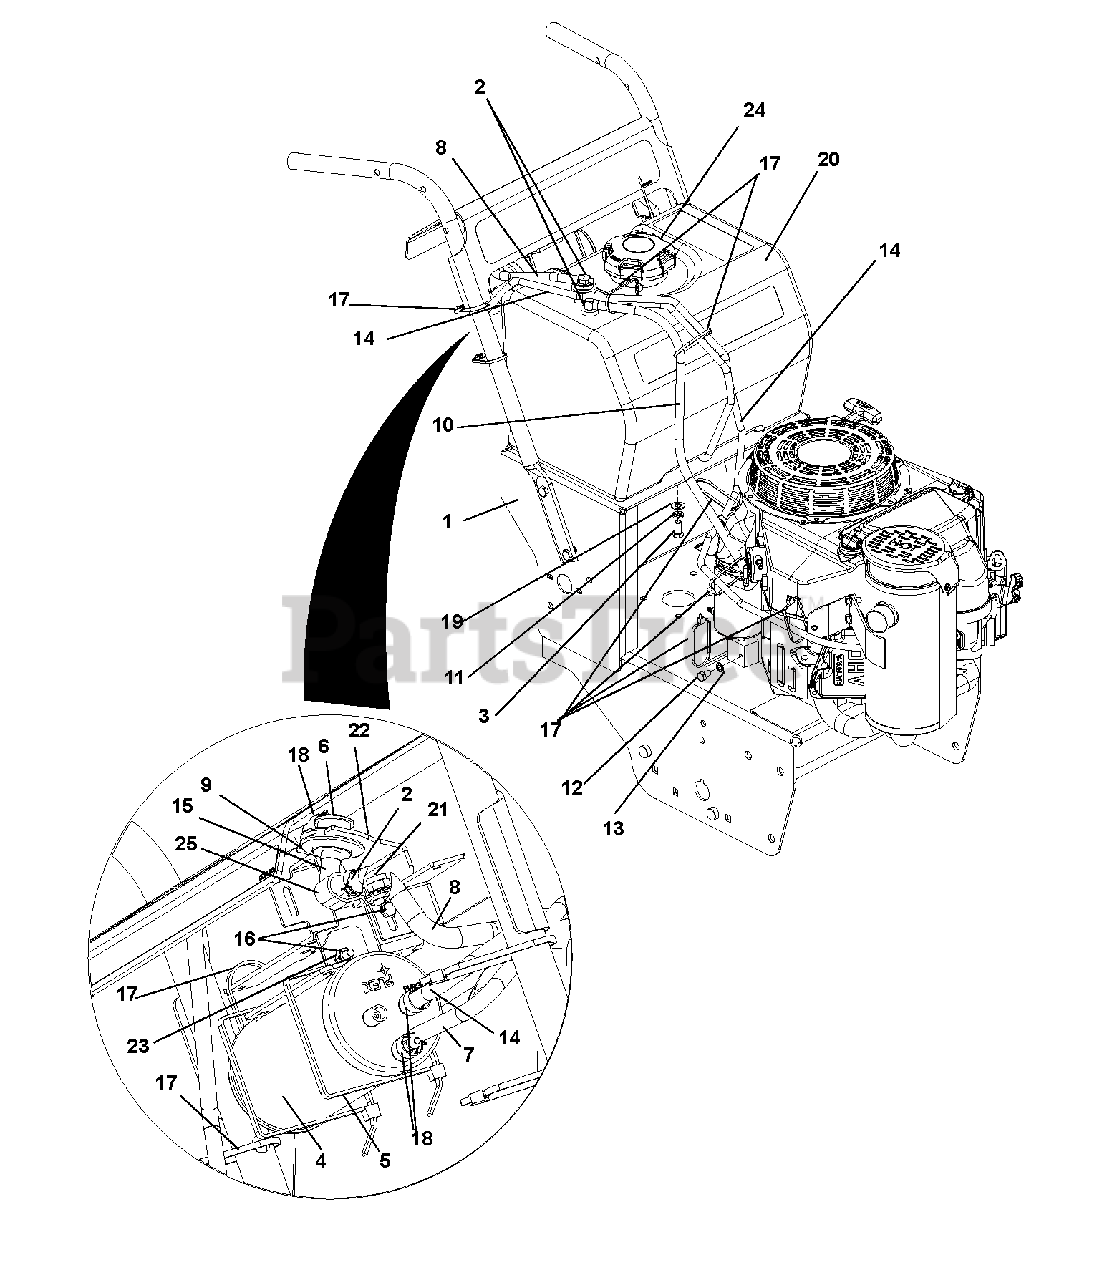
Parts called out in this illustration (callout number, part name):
1	Frame, Gravely GRWK w/Decals (SN 000101 – 020999)
2	Clamp, Fuel Line
3	Bolt, .38-16 x .75 Hex Grade 5
4	400 CC Carbon Canister 3/16 Point
5	Cable Tie, .19 x 14.4
6	Valve, Remote Roll Over
7	Hose, 3/16 Remote ROV-Canister
8	Hose, 1/4" Tank-Remote ROV GRW
9	Grommet, Remote ROV
10	Hose, Fuel .25 x 18.00
11	Washer-Locking .38 x .094 Regular
12	Bolt, Hex M8 x 1.25 x 14
13	Washer, Locking-EXT.326 x .599 x .031
14	Hose, Purge Line 3/16 GRWLK
15	Elbow Fitting, 1/4 x 1/4 Assembly
16	Screw, Machine 10-24 x .75 Hex Washer Head
17	Cable Tie, .15 x 8.50
18	Clamp, Hose, Spring .188
19	Washer, Flat .406 x .812 x .065
20	Assembly, Tank, Fuel FF CLPE Walk (SN 000101 – 020999)
21	Nut, Locking-Flange M8-1.25
22	Bracket, ROV and CC Gear Walk
23	Nut, Locking-Nylon 10-24 with Insert (SN 000101 – 019999)
24	Cap, Fuel Nonvent, Autolock
25	P-Clip, .500 Insulated
